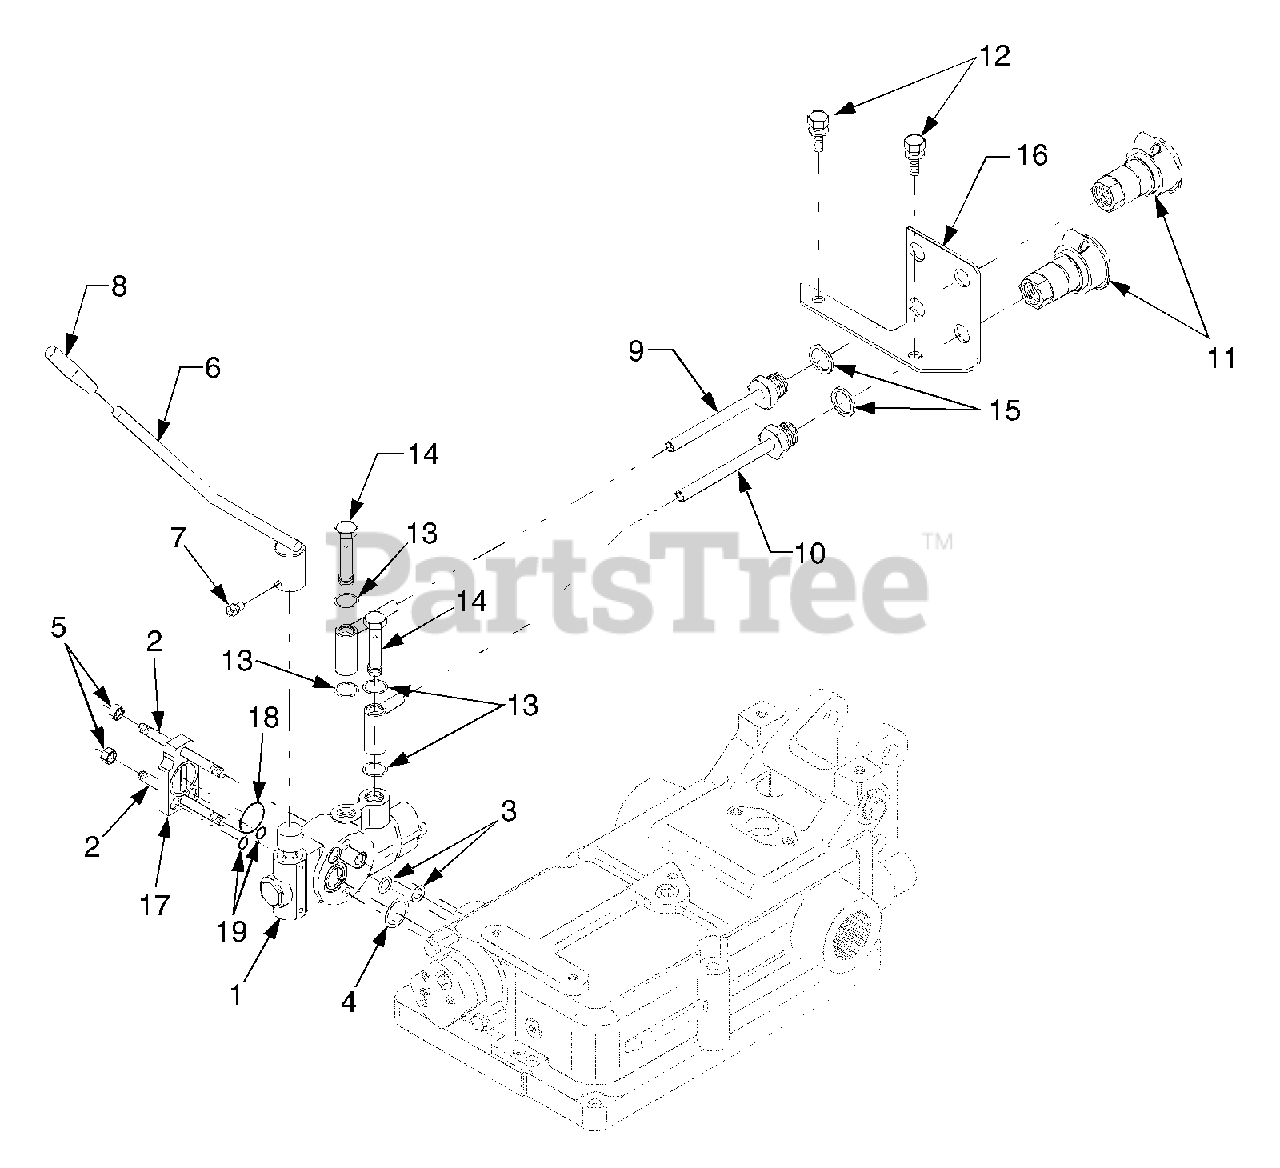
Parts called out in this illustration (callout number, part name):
1	Double Acting Valve (Detent)
6	Lever 3, Double Acting
8	Grip, Lever
9	Pipe A, Hydraulic
10	Pipe B, Hydraulic
11	Coupler Socket Ass'y
14	Bolt 2, Joint
16	Bracket, Socket
